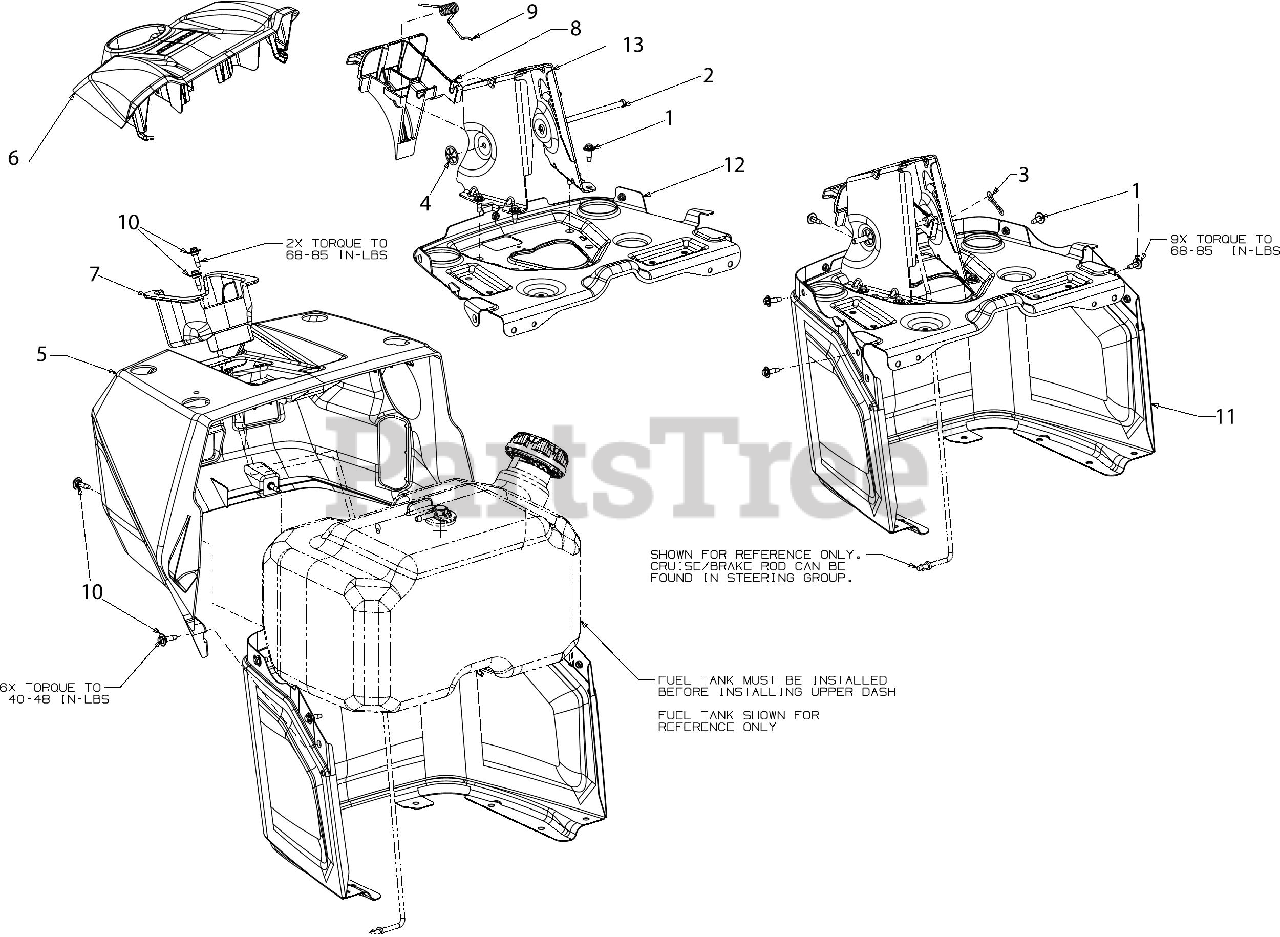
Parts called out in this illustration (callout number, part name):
1	SCREW M6-1 x .625
2	HINGE PIN .25 x 4.50
3	BOW TIE COTTER PIN 1/4-5/16
4	PUSH ON NUT
5	UPPER DASH
6	UPPER DASH CAP
7	STEERING SHAFT BEARING
8	CRUISE/BRAKE DASH LEVER
9	TORSION SPRING .330 ID
10	SHOULDER SCREW M6-1 .368 X.115
11	LOWER DASH
12	DASH/FUEL TANK PLATE
13	STEERING MOUNT BRACKET
